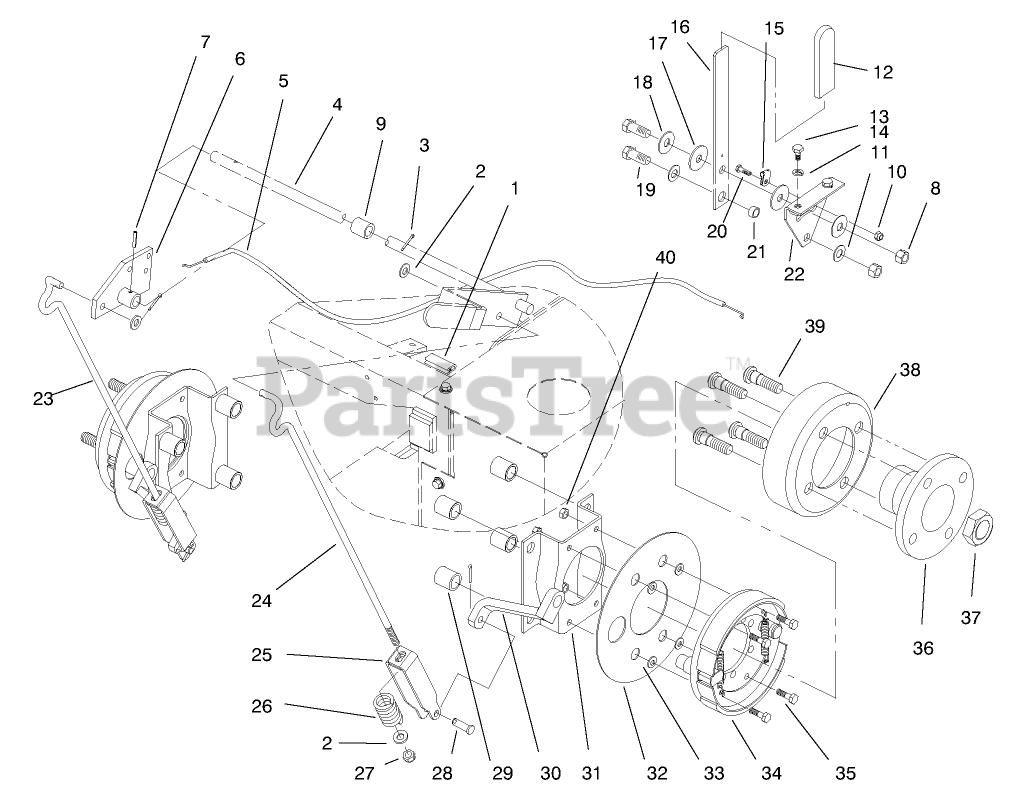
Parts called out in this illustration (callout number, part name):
1	EDGE TRIM
2	WASHER-PLAIN
3	PIN-COTTER
4	WA - BRAKE HANDLE B
5	ASSEMBLY - CONTROL
6	ASSY-PARKING BRK B
7	SPIROL PIN H D
9	SPACER-PARKING BR B
10	NUT-LOCK, NI
11	WASHER-FLAT
12	GRIP-HANDLE
13	SCREW-HH
14	WASHER-LOCK
15	CLAMP
16	Handle
17	FRICTION WASHER
18	WASHER-SPRING DISC
19	SCREW-HH
21	SPACER CLUTCH ARM
22	CONTROL BRACKET WA B
23	ROD - RH BRAKE
24	ROD - LH BRAKE
25	Clevis-Brake
26	SPRING - COMPRESSION B
27	NUT-LOCK
28	PIN-CLEVIS
29	SPACER
30	WA - BRAKE LEVER B
31	Bracket-Brake
32	SHIELD-BRAKE, GRASS
33	WASHER-FLAT
34	BrakeASM
35	SCREW-HH
36	Hub-Wheel
37	NUT-LOCK
38	DRUM-BRAKE
39	STUD-DRIVE
40	NUT-LOCK, NI
